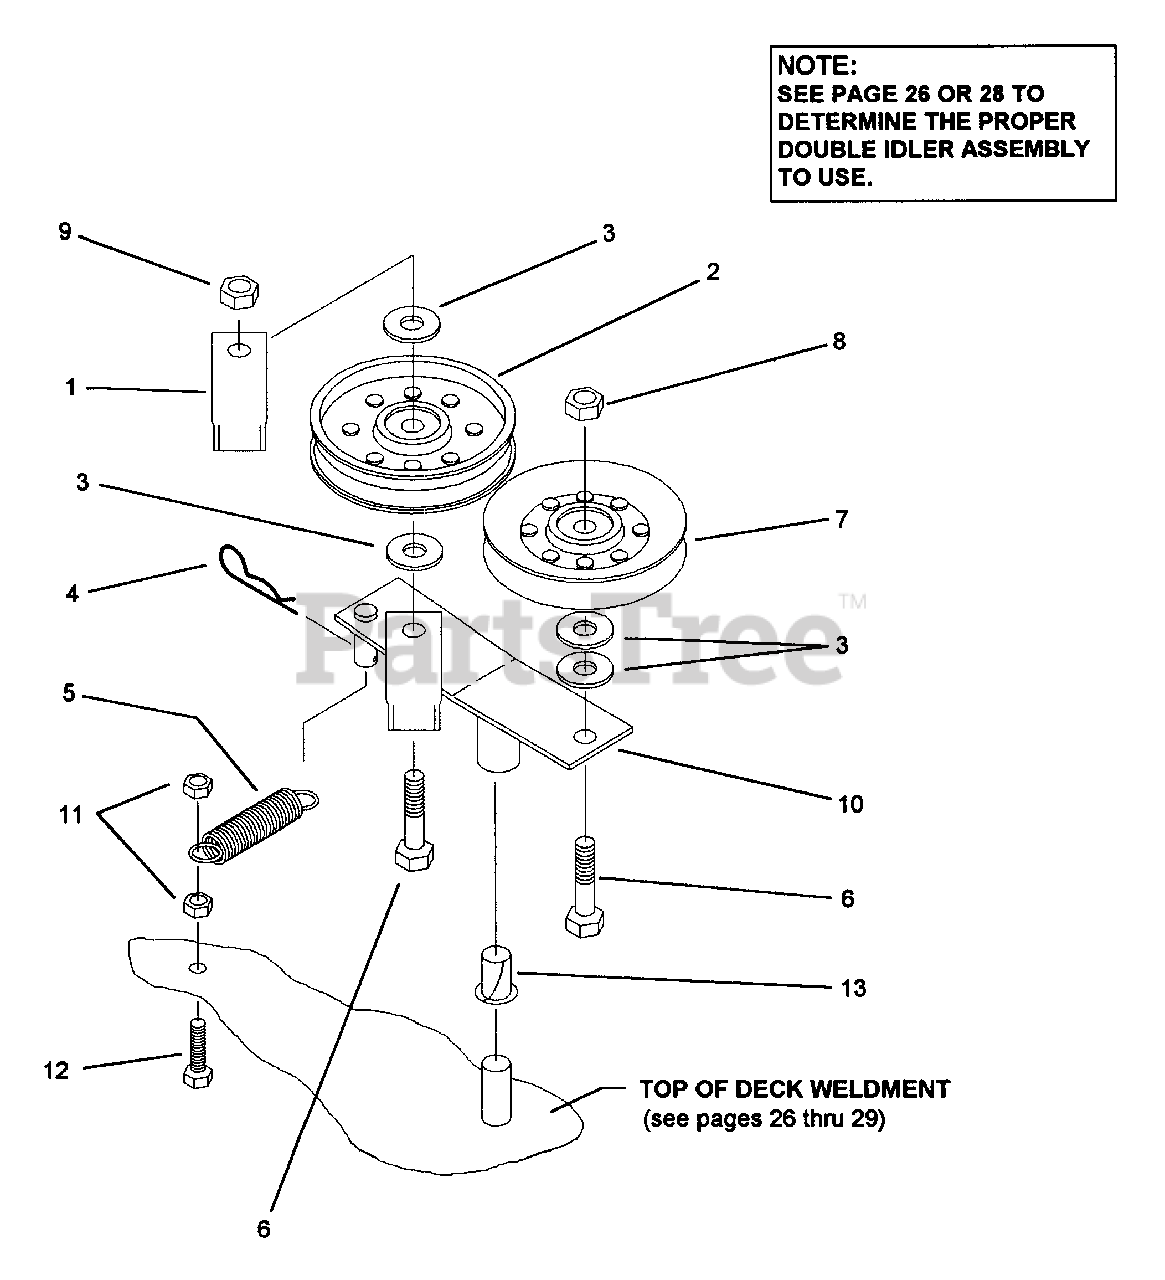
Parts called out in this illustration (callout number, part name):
1	PLATE, BELT STOP
2	PULLEY, FLAT IDLER 1/2 BORE, 4" O.D.
3	WASHER, FLAT STD. 1/2"
4	PIN, HAIR SPRING, 1/8 X 2-1/2"
5	SPRING EXTENSION, 3/4 X 4" O.A.L.
6	BOLT, 1/2-13 X 2" GR. 5
7	PULLEY, V-IDLER, 1/2 BORE, 4-3/8 O.D.
8	NUT, 1/2-13, NYLOC
9	NUT, 1/2-13, STOVER
10	DOUBLE IDLER WELDMENT
11	NUT, 3/8-24, M-F LOCKNUT
12	BOLT, 3/8-24 X 1-1/4" GR. 5
13	BUSHING, NYLON, 5/8" BORE
